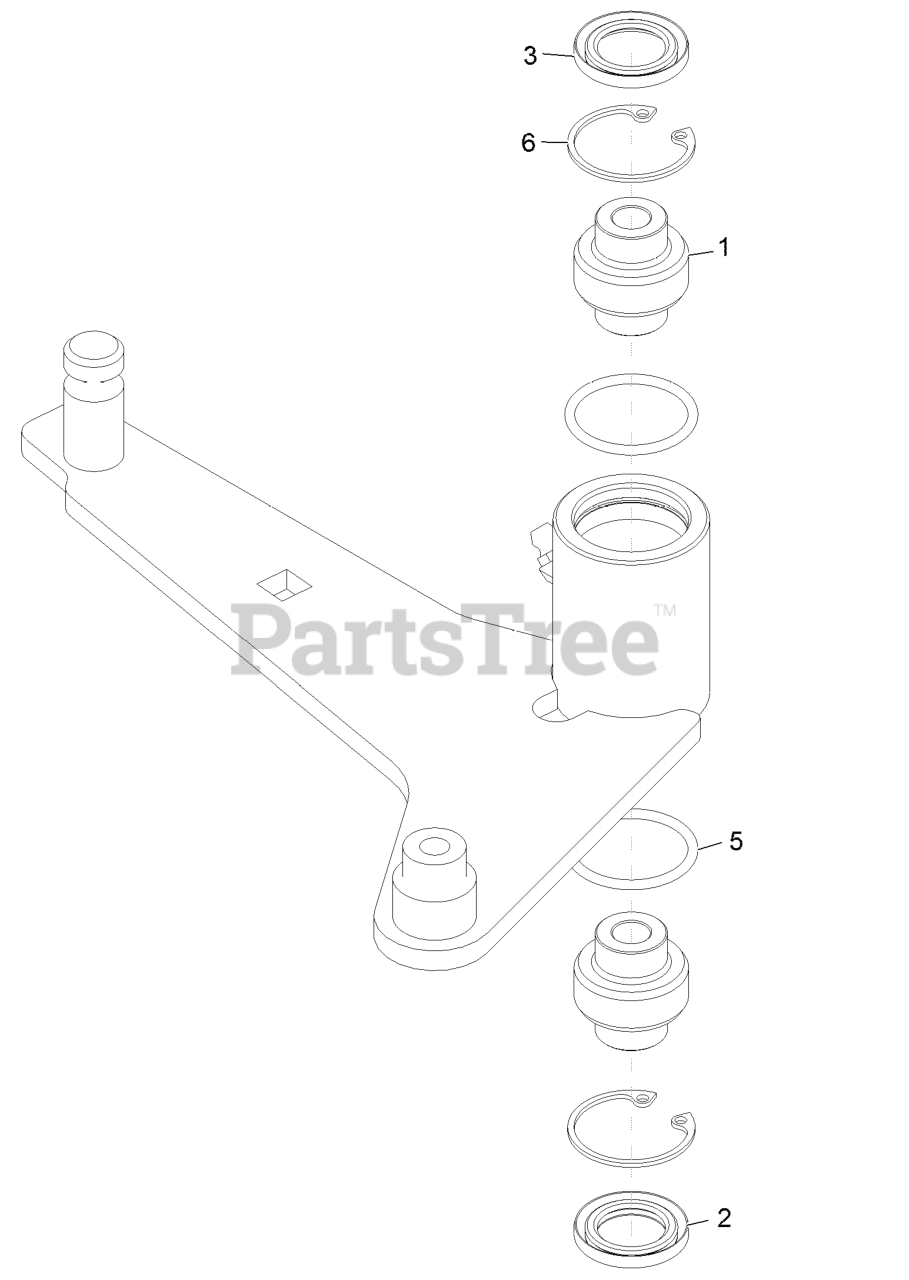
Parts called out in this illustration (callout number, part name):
1	BEARING-SPHERICAL
2	SEAL-LIP, DOUBLE
3	SEAL-LIP, SINGLE
6	RING-SNAP
